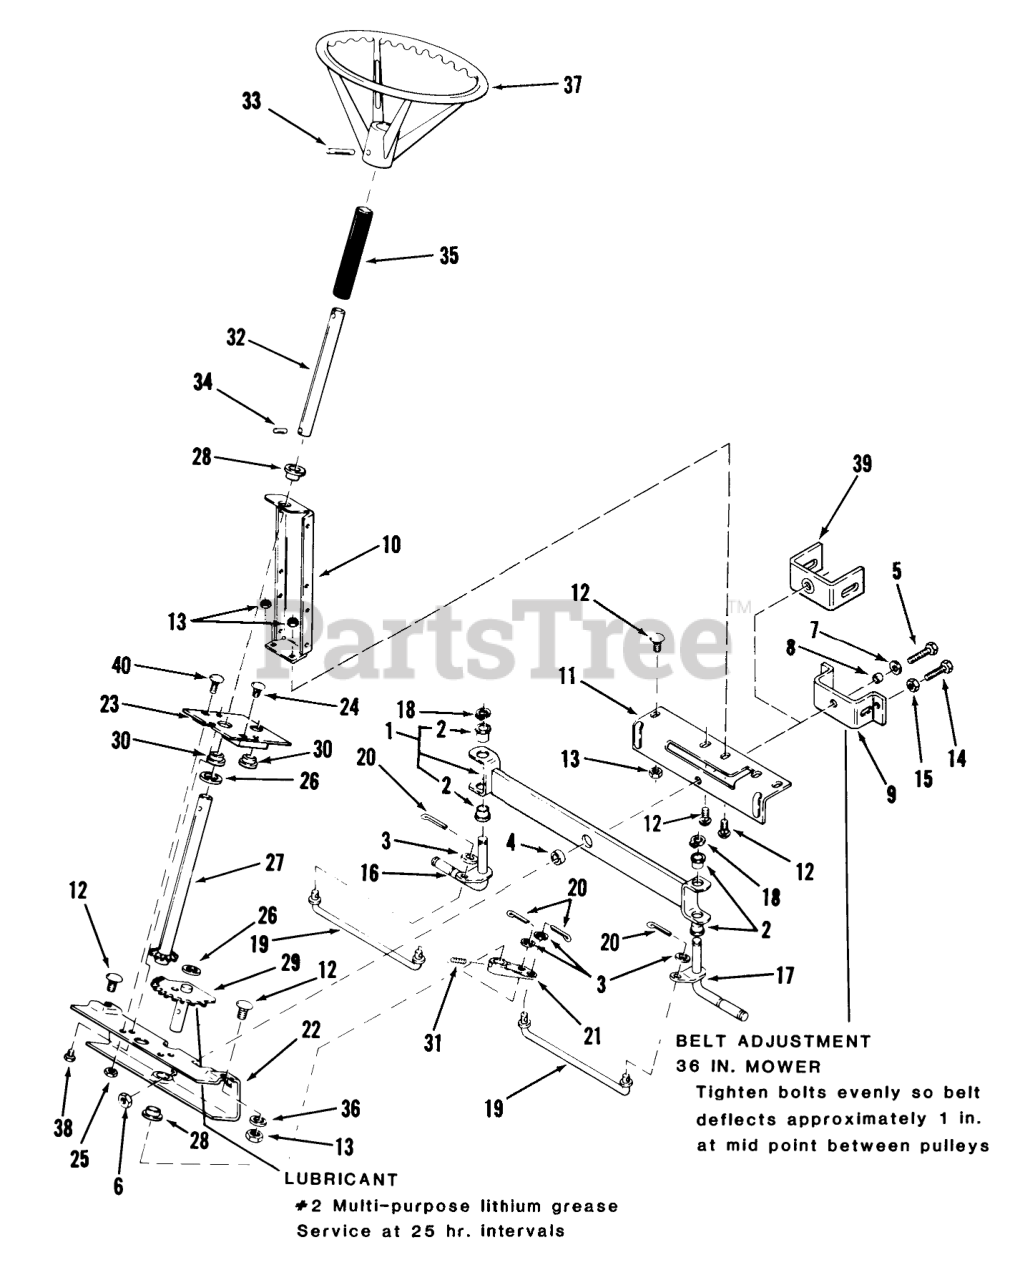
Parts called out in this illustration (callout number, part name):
1	ASSY-FRNT AXLE/BRG
2	BUSHING
3	Washer
4	Spacer
5	Bolt 1/2-13 X 2
6	Eslok Nut
7	Washer
8	BUSHING
9	Pivot-Mower
10	Support-Steering
11	SUPPORT-FRNT AXLE RE
12	Bolt-Carriage
13	Nut
14	SCREW-HH
15	Nut
16	ASSY-SPINDLE RH R
17	ASSY-SPINDLE LH R
18	Snap Ring
19	ROD-STEERING
20	Pop Rivet
21	ARM-STEERING
22	SUPPORT-FRONT AXLE
23	Plate-Reinforcing
24	Bolt
25	Nut
26	Washer
27	Steering Shaft
28	BEARING
29	ASSY-STEERING SEC R (NS)
30	BUSHING
31	PIN-ROLL, SPIROL
32	TUBE-STEERING
33	Pin-Roll
34	SPIROL PIN
35	Steering Shaft Ext. Cover
36	Washer
37	Steering Wheel
38	Bolt
39	Pivot
40	Bolt
